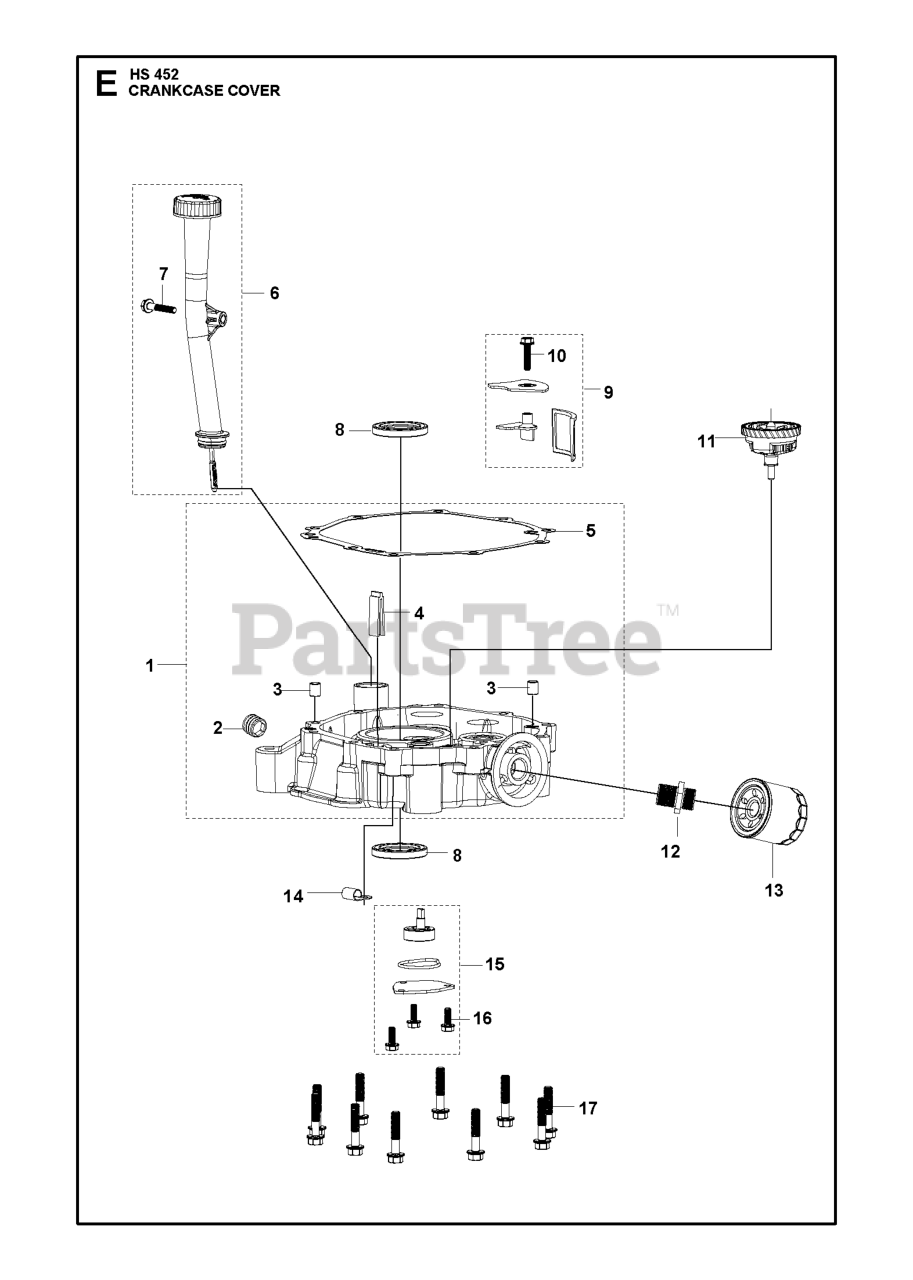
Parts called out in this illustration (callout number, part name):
1	CRANKCASE KIT CRANKCASE COVER
2	OIL PLUG OIL PLUG
3	PIN LOCATION PIN
4	BLOCK OIL RETURN BLOCK
5	GASKET CRANKCASE COVER GASKET
6	SERVICE KIT KIT.FILL.TUBE (KIT
7	BOLT GB/T 5789: M6 L=35
8	SEAL OIL SEAL
9	STRAINER OIL STRAINER
10	BOLT GB/T 5789: M6 L=25
11	SERVICE KIT KIT.COMPONENTS OF
12	OIL PLUG OIL FILTER MOUNTING P
13	FILTER OIL FILTER (ENG.452)
15	OIL PUMP ASSY OIL PUMP ASSY
16	Husqvarna TBD
17	BOLT T370: M8 L=40 S=12
